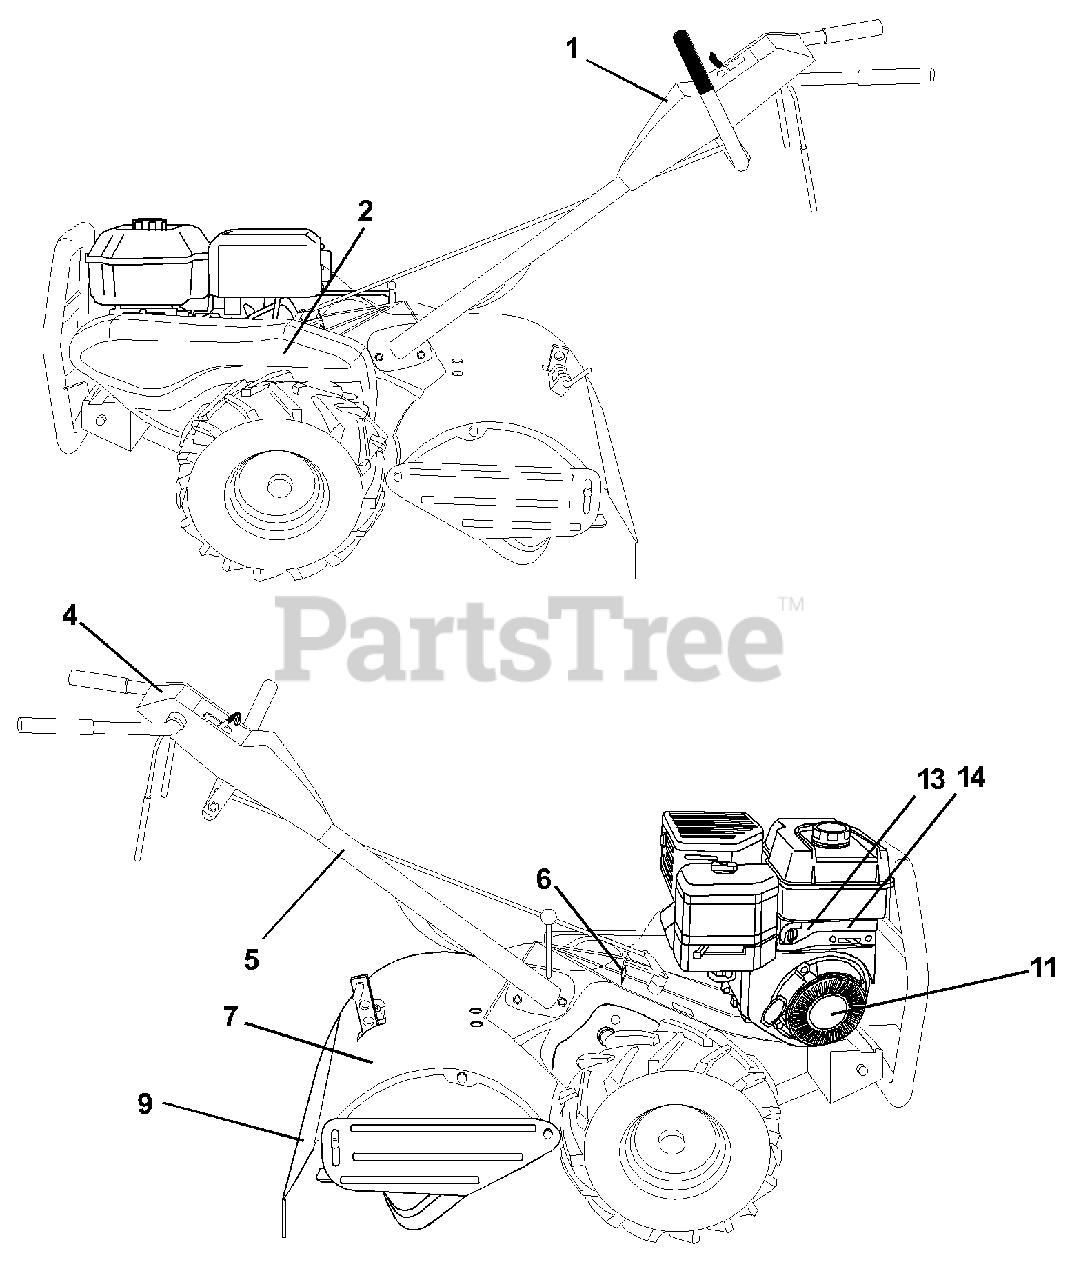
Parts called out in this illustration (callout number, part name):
1	Decal, Logo
2	Decal, Logo
4	Decal, Instruction, Tilling
5	Decal, Hand Placement
6	Decal, Shift Indicator
7	Decal, Warning
9	Decal, Warning, Rotating Tines
11	Decal, HP
13	Decal, Rewind
14	Decal, Non-Intek IC
